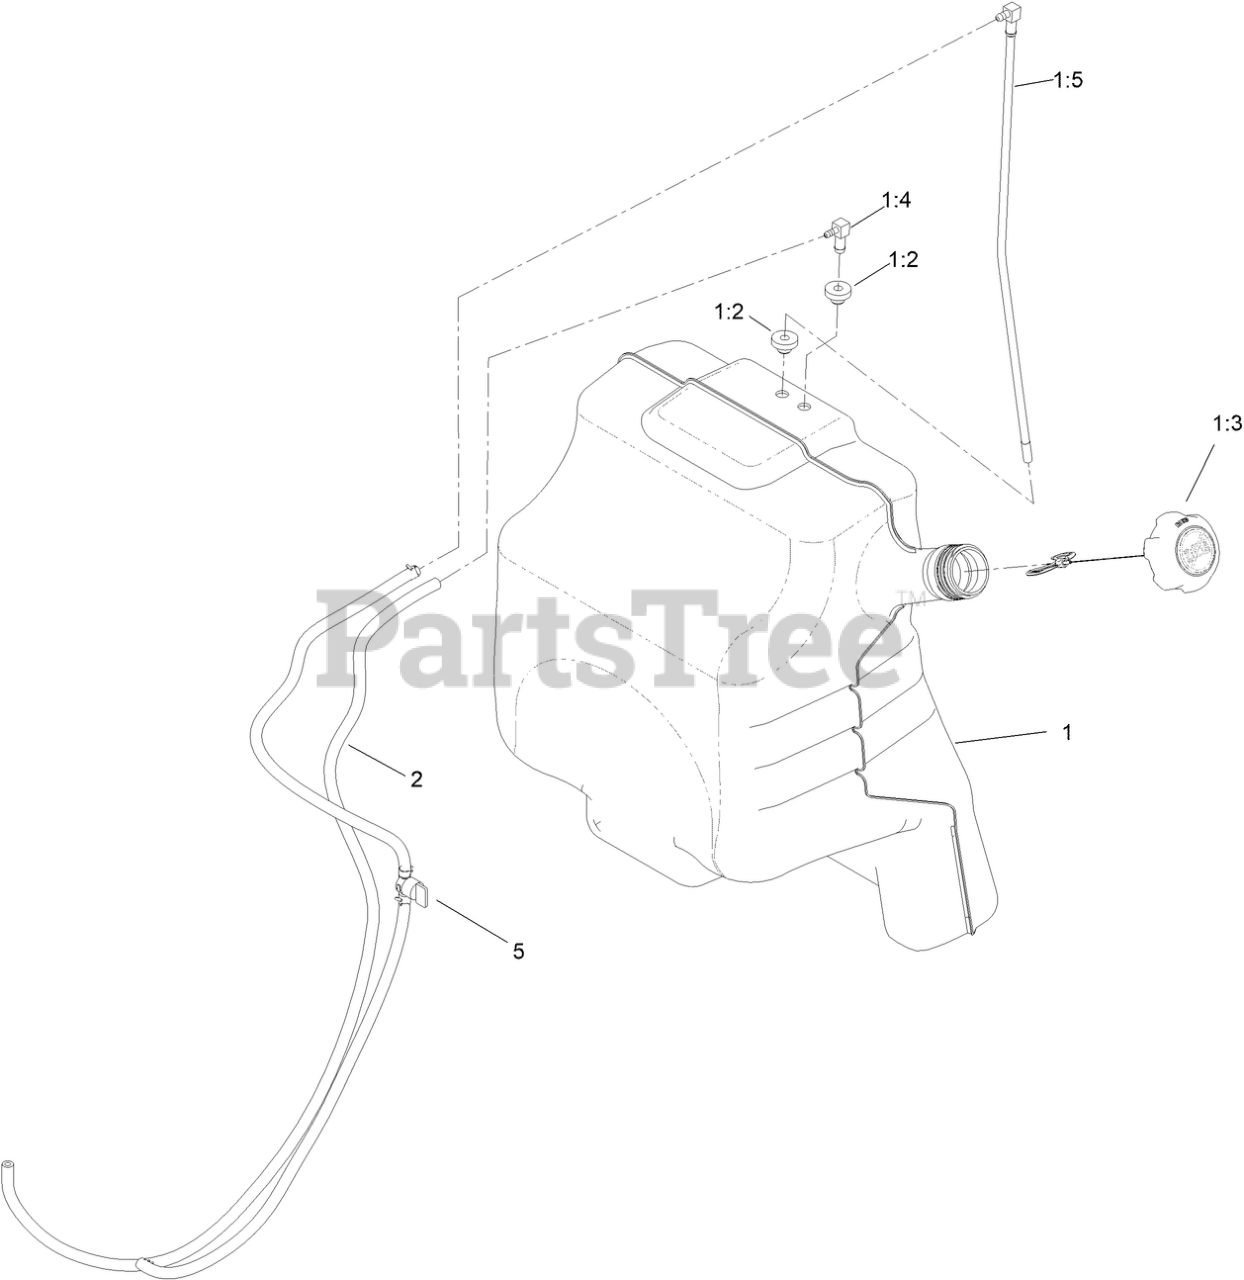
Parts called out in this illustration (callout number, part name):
1	FUEL TANK ASM
1:2	BUSHING
1:3	CAP-FUEL
1:4	FITTING-ELBOW, 90 DEG
1:5	ASM, TUBE-FUEL
2	HOSE-FUEL
5	FUEL LINE ASM
